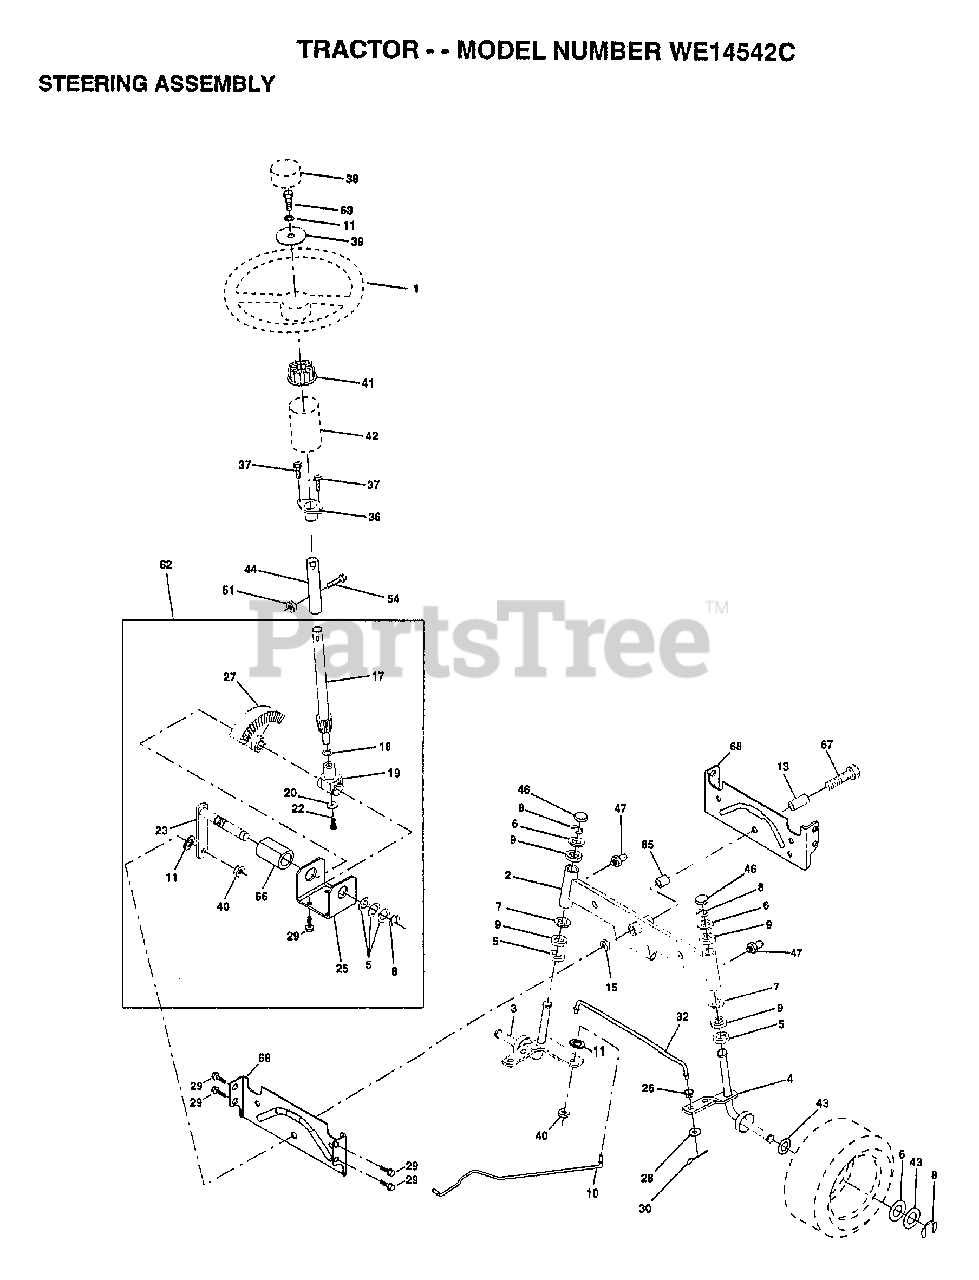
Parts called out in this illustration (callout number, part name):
2	AXLE ASM
5	WASHER .T
6	WASHER
7	WASHER
8	RING
9	COL. SRTG. BEAR.
10	DRAGLINK-STAMPED
13	BEARING AXLE
14	BOLT HEX 5/8-11
15	"NUT-LOC,FLANGE LT"
16	AXLE PIN
17	SHAFT ASSM STEERN
18	THRUST WASHER
19	SUPPORT.SHAFT
21	SCREW HEX SOC1/4-
24	NYLINER T
25	BRKT-STEERING
26	BUSHING.DRAGLINK
27	GEAR SECTOR
28	WASHER
29	SCREW
32	TIE ROD
36	BUSHING.STEERING
37	"SCREW-TT,10-32 FL"
38	CAP WHL STR SEARS
39	WASHER T
41	ADAPTER-WHEEL LT
42	BOOT STR SHAFT
43	WASHER
46	CAP
47	ZERK M
62	STEERING ASM KIT
65	SPACER AXLE
66	"BEARING-ARM,PITMA"
67	BOLT
68	BRACE AXLE
